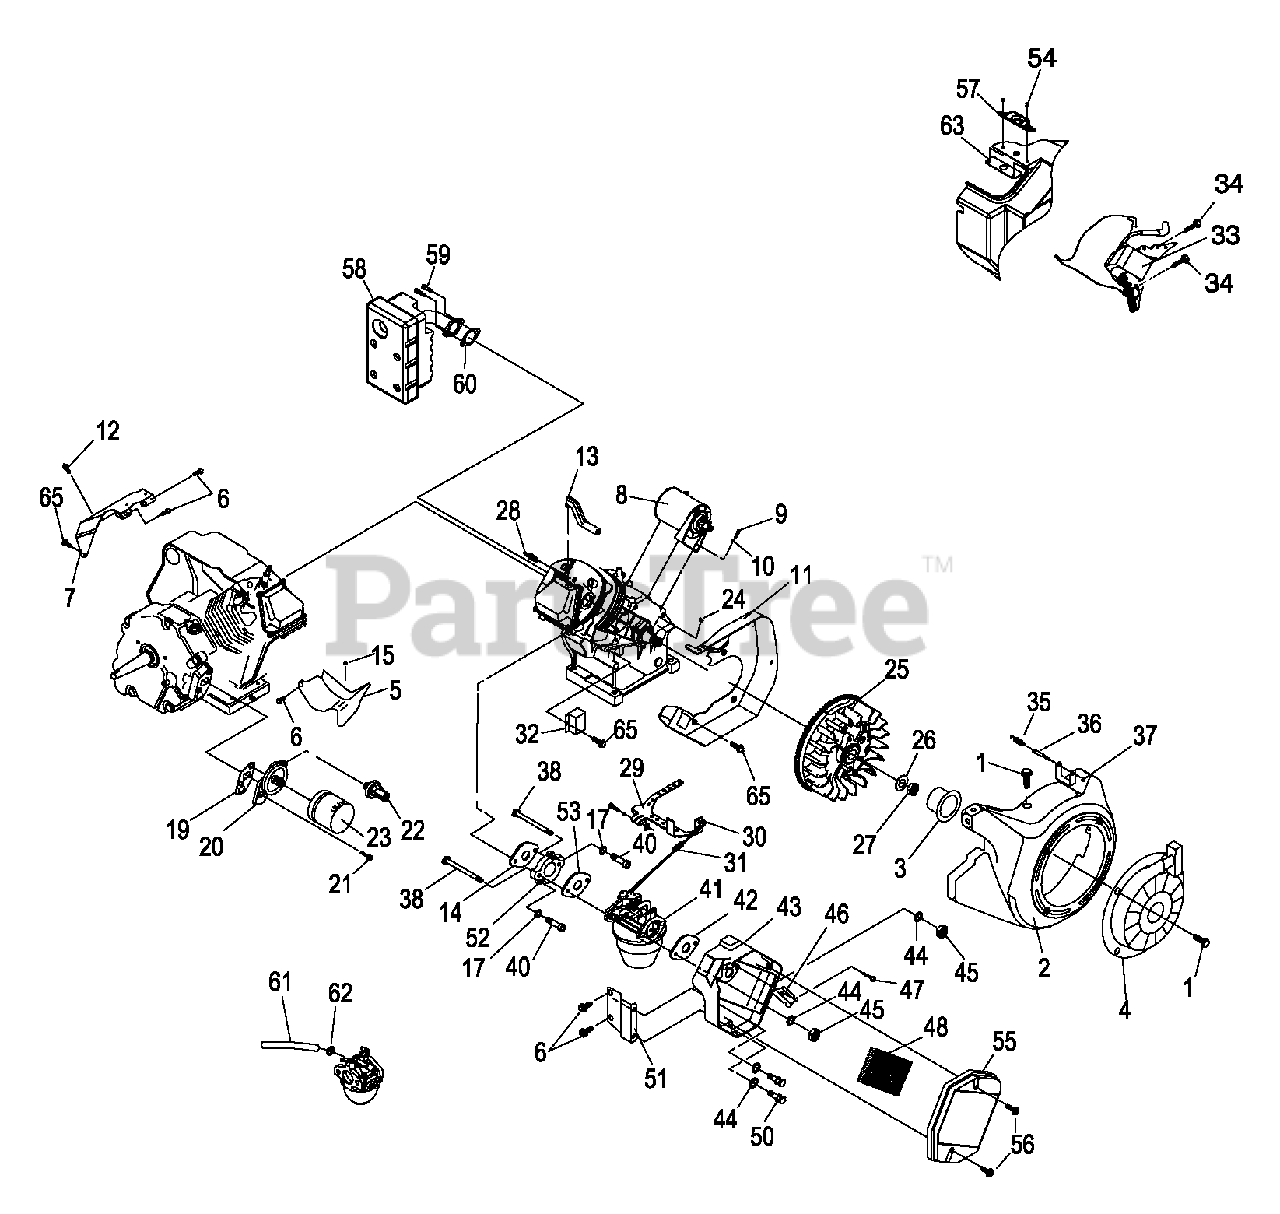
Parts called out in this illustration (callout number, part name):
1	SCREW HHTT M6-1.0 X 8 ZYC
2	ASSEMBLY, BLOWER HOUSING
3	PULLEY STARTER LARGE FRAME
4	RECOIL STARTER LARGE FRAME
5	WRAPPER, BOTTOM 12 HP HS
6	SCREW HHTT M6-1.0 X 10 YELLOW CHROME
7	WRAPPER, TOP REGULAR STEEL
8	ASSEMBLY, STARTER 46
9	SCREW SHC M8-1.25 X 40
10	WASHER, LOCK M8-5/16
11	BACKPLATE, W/ ELECTRIC START
12	SCREW, HHTT 5/16 – 18 X 1/2" CLEAR
13	HOSE, BREATHER GH410 ENGINES
14	GASKET, INTAKE ADAPTER
15	GROMMET 9/16 X 1/16 X 7/16
16	ASSEMBLY, WIRE #0-4.5" LONG
17	WASHER, LOCK M6-1/4
19	GASKET,OIL FILTER ADAPTER
20	ADAPTER OIL FILTER W/TAPD HOLES
21	SCREW, SHC M8-1.25 X 30 G12.9
22	SWITCH, HOBBS OIL PRESSURE 5PSI
23	FILTER, OIL BLACK 75 LONG
24	KEY, WOODRFF 4 X 19D
25	FLYWHEEL, WITH RING GEAR 27 DEGREE
26	WASHER,BELV-20 X 2.2
27	NUT HEX M20-1.5 G8 YLW CHROME- FLYWHEEL
28	SPARKPLUG, CHAMPION RC14YC
29	ASSEMBLY,GOVERNOR LEVER 12HP
30	ROD, GOVERNOR CONTROL
31	SPRING, ANTI-LASH
32	OIL PRESSURE SHUTDOWN MODULE
33	ASSEMBLY, IGNITION ADV NO DIODE GH410
34	SCREW HHFC M6-1.0 X 25
35	SPRING GOVERNOR 320/360/410
36	BOLT, GOVERNOR ADJUSTMENT M5
37	NUT, HEX LOCK M5-0.8 NYLON INSERT ZINC
38	BOLT, CARBURETOR MOUNTING
40	SCREW, SHC M6-1.0 X 20 G12.9 ZINC PLATED
41	CARBURETOR ASSEMBLY, 410HS
42	GASKET, AIR CLEANER
43	BASE, AIR CLEANER 410 HI FLOW XP PORT
44	WASHER, FLAT M6
45	NUT, HEX LOCK M6-1.0 NYLON INSERT
46	PLATE, SPITBACK
47	SCREW, PLASTITE #8 X .37 LONG
48	ELEMENT, AIR FILTER
50	SCREW, HHC M6-1.0 X 16 W/ LOCK WASHER
51	BRACKET, AIR CLEANER
52	ADAPTER, "K"
53	GASKET, CARBURETOR/MANIFOLD
54	RIVET, 1/8"
55	COVER, AIR CLEANER 13GN
56	BOLT, AIR CLEANER COVER
57	BRACKET, CHOKE CABLE
58	MUFFLER, 410 SIDE-OUT ALUMINIZED
59	SCREW, SHC M8-1.25 X 20 SEMS
60	GASKET, EXHAUST
61	HOSE,1/4" SAE30R7 SETIFLEX 13"
62	CLAMP, HOSE WORM GEAR
63	BACK PLATE
65	SCREW HHFC M6-1.0 X 12
